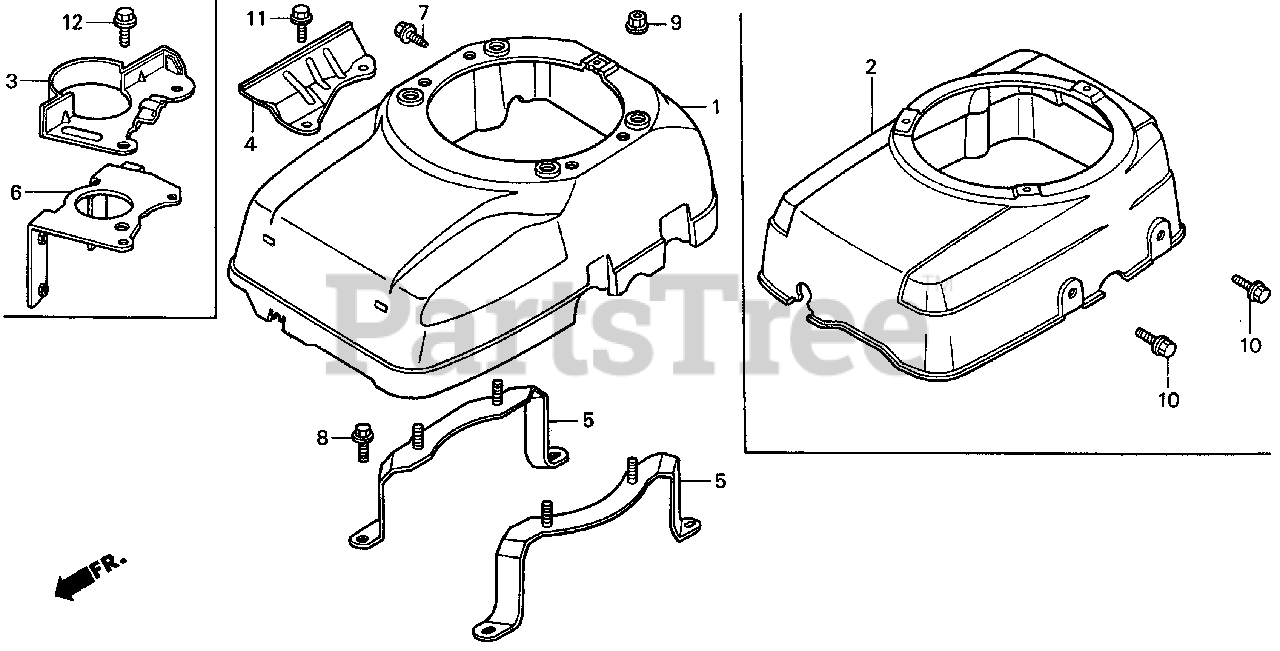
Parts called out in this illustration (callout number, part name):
1	COVER, FAN *NH1* (BLACK)
1	COVER, FAN *R8* (BRIGHT RED)
5	BRACKET, FAN COVER
7	BOLT, FLANGE (6X12) (CT200)
8	BOLT, FLANGE (6X16)
9	NUT, FLANGE (6MM)
